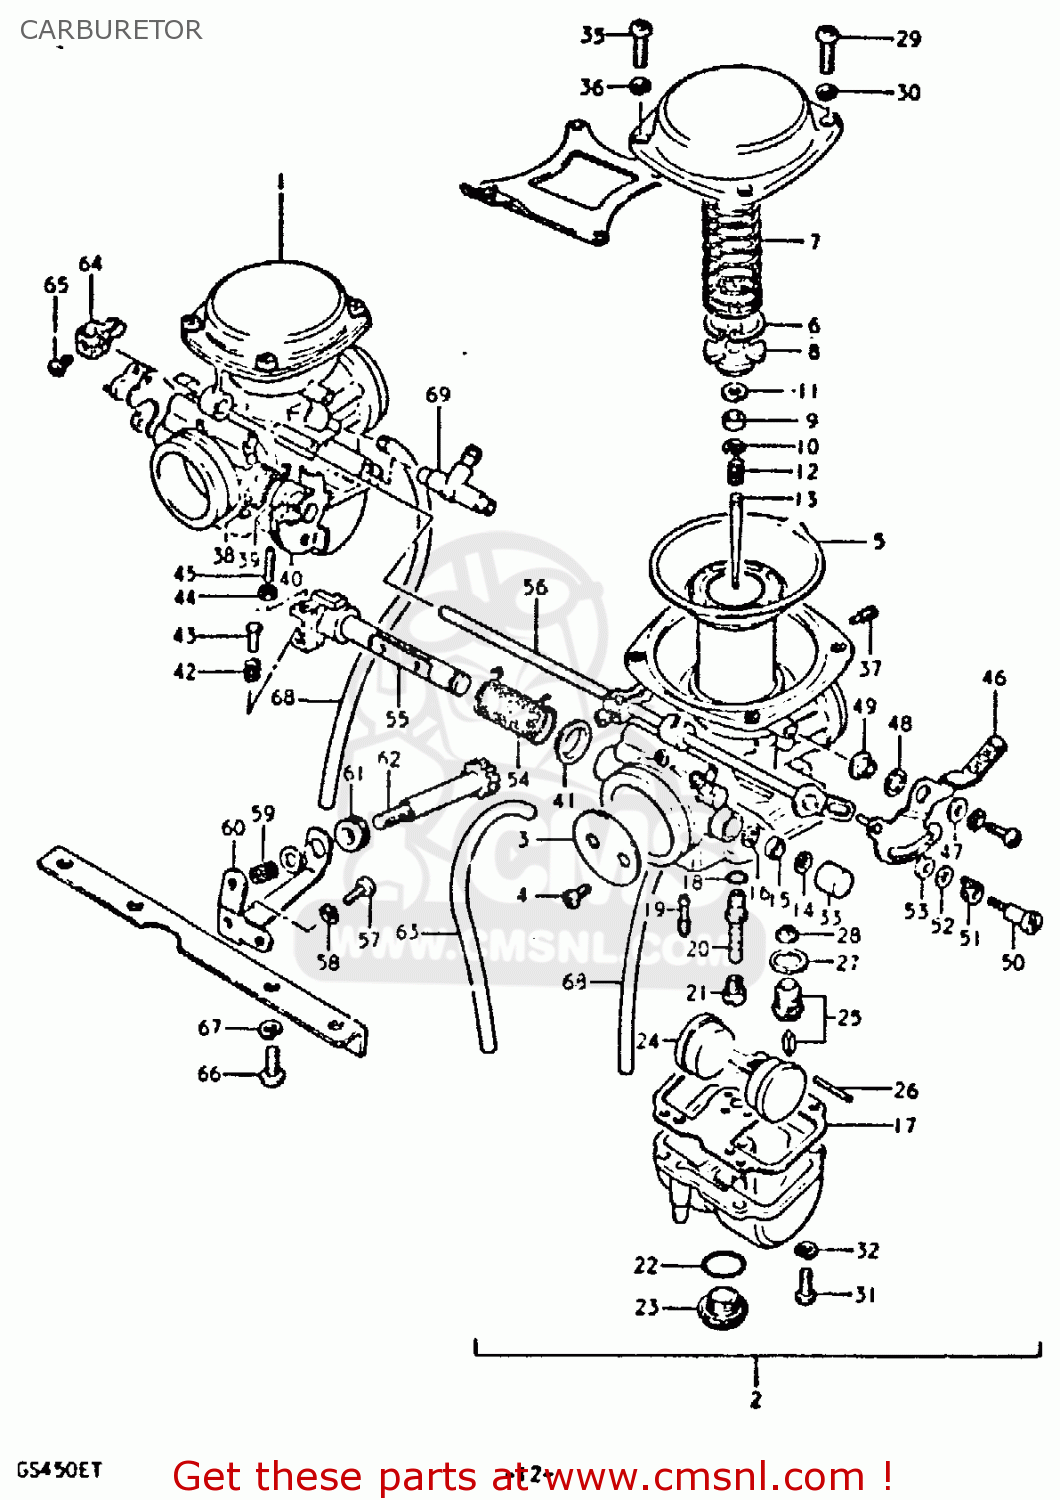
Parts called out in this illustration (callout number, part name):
1	CARBURETOR ASSY, RH
2	CARBURETOR ASSY, LH
3	VALVE,THROTTLE
4	SCREW
5	DIAPHRAGM
6	E RING
7	SPRING,DIAPHRAGM
8	HOLDER,GUIDE
9	RING
10	CLIP
11	WASHER
12	SPRING
13	NEEDLE, JET (4C3-3)
14	E RING
15	GASKET,THROTTLE SHAFT (NAS)
16	SEAL
17	GASKET,FLOAT CHAMBER (NAS)
18	O-RING
19	JET, PILOT (17.5)
20	JET, NEEDLE (Y-6)
21	JET,MAIN
22	O-RING
23	SCREW,GUIDE
24	FLOAT
25	VALVE ASSY,NEEDLE
26	PIN,FLOAT
27	GASKET,MAIN JET HOLDER (NAS)
28	FILTER
29	SCREW
30	LOCK WASHER
31	SCREW
32	LOCK WASHER
33	CAP
34	GASKET
35	SCREW
36	LOCK WASHER
37	JET,AIR(1.6)
38	SPRING
39	RING
40	SHAFT ASSEMBLY
41	RING
42	SPRING,THROTTLE SCREW
43	PIN,THROTTLE LEVER
44	NUT
45	SCREW
46	LEVER,STARTER
47	WASHER,STARTER LEVER (4.1X12X0.8)
48	WASHER,STARTER LEVER
49	RING,STARTER LEVER
50	SCREW
51	SPRING,STARTER LEVER S
52	WASHER
53	WASHER
54	SPRING
55	SHAFT ASSEMBLY
56	SHAFT,STARTER
57	SCREW
58	LOCK WASHER
59	SPRING
60	BRACKET,THROTTLE ADJUST
61	BUSHING,THROTTLE ADJUSTER
62	SCREW
63	HOSE (4.5*8*180)
64	ARM, STARTER
65	SCREW
66	SCREW 6X12
67	LOCK WASHER
68	HOSE
69	NIPPLE
